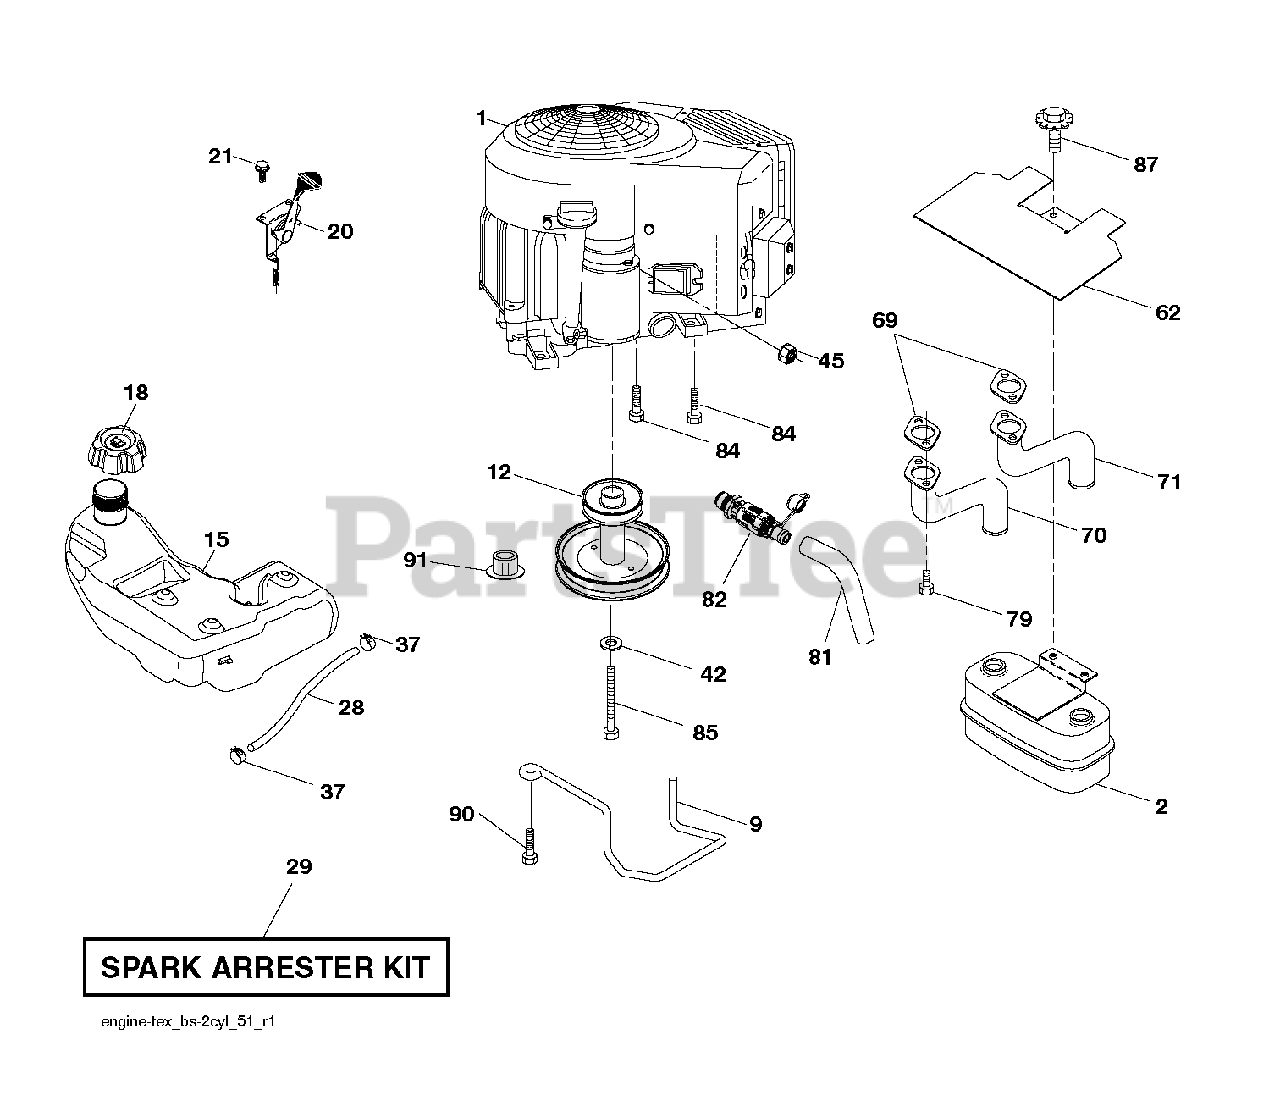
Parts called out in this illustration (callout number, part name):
2	MUFFLER.TWIN.CYL.LOW.TONE
9	KEEPER.BELT.ENGINE.4.2
12	PULLY ENGINE
15	TANK.ASSY.3.GAL.EPA
18	CAP ASM.FL.RTCHT.3"GRY.E10
20	CONTROL.TH/CK.COBRA.B&S.TWN.
21	SCREW.#10 X 0.750.BOS THREAD
28	Fuel Line
29	ARRESTER SPARK (OPTIONAL)
42	LOCKWASHER
45	NUT
62	SHIELD.HEAT.MUFFLER
69	GASKET.MUFFLER
70	EXHAUST TUBE LH *SUBS/2*
71	EXHAUST TUBE RH
79	SCREW.SOCKET.HEAD.5/16-18
81	TUBE, DRAIN OIL ASM.
82	VALUE.OIL.DRAIN
85	BOLT HEX 7/16-20X4-1/4"
87	BOLT, 5/16-18 X 1 3/4
90	SCREW 3/8-16X1
91	BUSHING.1.375OD
